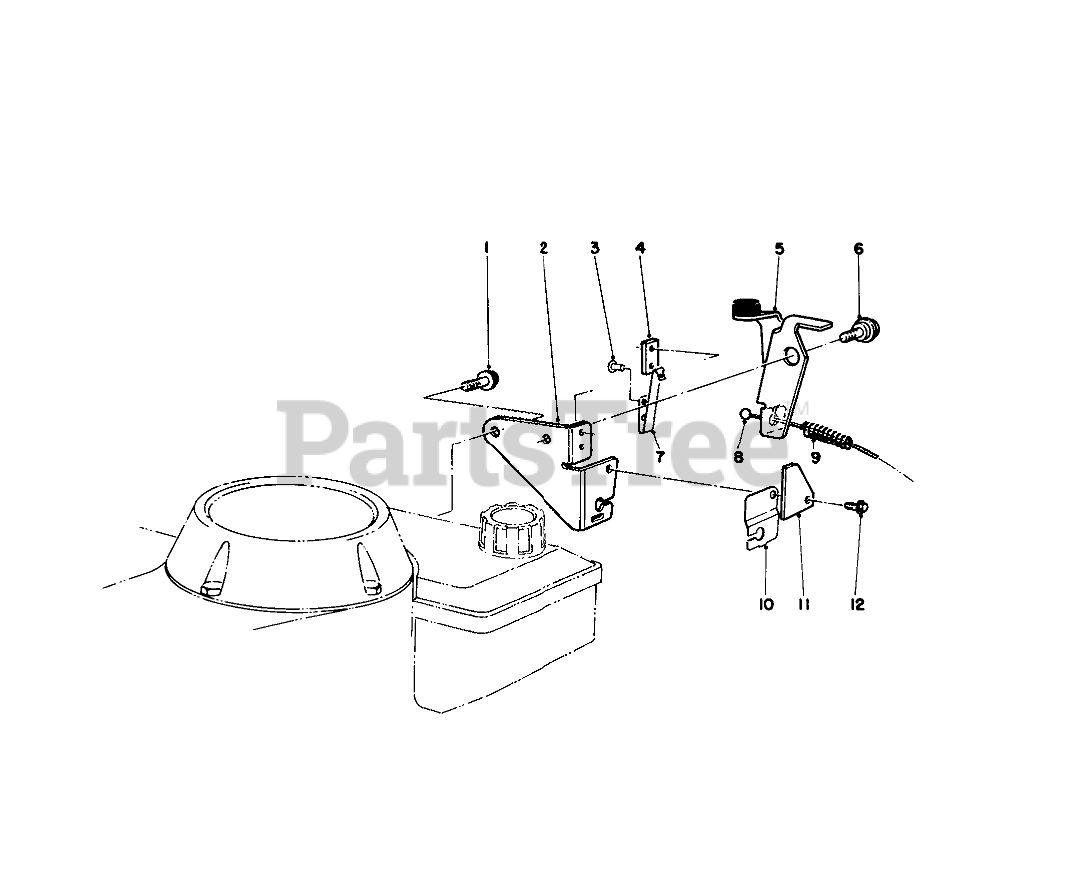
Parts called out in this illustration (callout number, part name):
1	THO FORM SCREW M6 X 1
2	Plate-Mounting
3	RIVET-PLASTIC
4	Strap-Insulation
5	BRAKE PLATE ASM
6	Screw-Shoulder
7	STRAP-GROUND
8	BRAKE CABLE
9	SPRING-COMPRESSION
10	CABLE CLAMP
11	STOP-GROUND STRAP
12	SCREW
